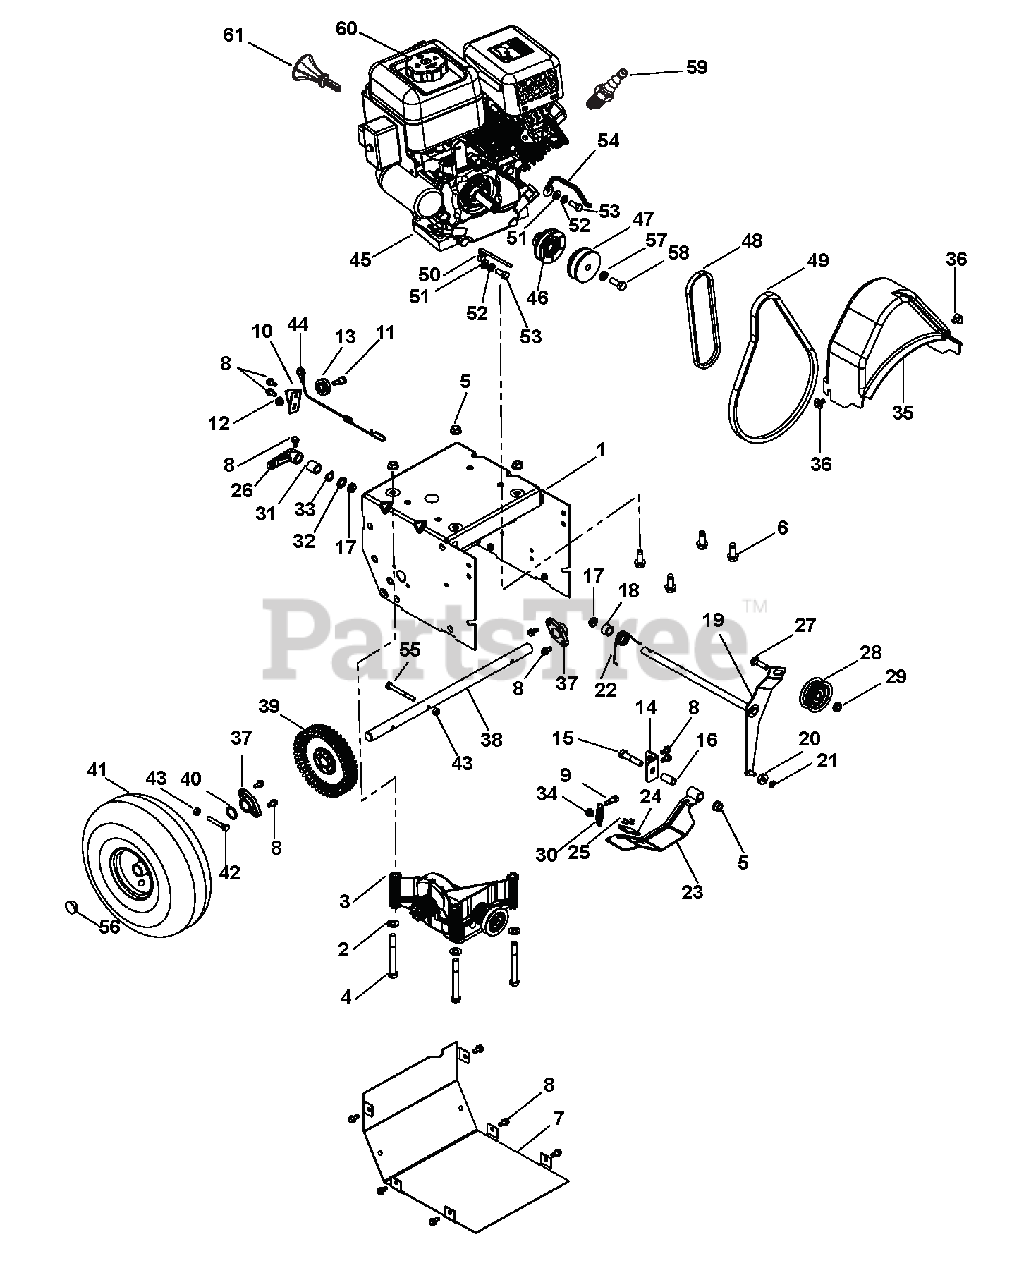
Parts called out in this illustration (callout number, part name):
1	FRAME, WELDMENT
2	@WSHR-FL-STL.406X.812X.065 YWZ
3	TRANSMISSION, GT HO W/PULLEY
4	@BLT-HEX .38-16X3.50 GR5 YWZC
5	@NUT-LK-TOP-FLG .38-16 YWZC
6	SCR-TAP .38-16X1.0 HWH YZ W/VT
7	COVER, BOTTOM
8	SCR-TAP .25-20X.50 HWH TR YWZ
9	BLT-SHLDR .31X.50 .25-20X.438
10	BRACKET, CABLE PULLEY
11	BOLT, SHLDR-.375X.375X.25-20
12	@NUT-LK-CTR-FLG .25-20 YWZC
13	PULLEY, CABLE
14	BRACKET, MOUNT - BRAKE
15	@BLT-HEX .38-16X1.75 GR5 YWZC
16	BSHG-SLV .385X.500X1.045
17	BUSHING, POLYLINER-.50 SNAPIN
18	BSHG-SLV .510X.751X.475
19	WELDMENT, ATTACHMENT IDLER ARM
20	BSHG,SLV .270 X .750 X .250
21	RG-RTNG-EXT .250X.010
22	SG-TORS .067X.88
23	BRAKE ARM W/PAD
24	PAD, BRAKE
25	RVT-POP .187 YZ
26	ARM, CLUTCH - ATTACHMENT
27	@BLT-RHDSHSQNK.31-18X1.25 G5YZ
28	KIT, FLAT IDLER
29	@NUT-LK-TOP-FLG .31-18 YWZC
30	SG-TENS .06X.46X2.00
31	BSHG-SLV .510X.751X.750
32	WSHR-FL-STL .52X.827X.062 YWZC
33	WSHR-WAVE .50X.75X.015 .13FRHT
34	@NUT-SPNLK-FLG .25-20 YWZC
35	COVER, BELT
36	SCR-TAP .25-20X.50 LGHWH TR YZ
37	BSHG .75X1.125X.65
38	SHAFT, AXLE - SINGLE SPEED
39	GEAR, AXLE 45T POLYMER
40	WSHR-FL-STL .754X1.000X.032 YZ
41	TIRE/WHEEL, 4.10-4
42	BLT-HEX .25-20X1.75 GR8 YWZC
43	@NUT-LK-CTR .25-20 YWZC
44	CABLE, LOWER TRACTION,SS & PRO
45	ENGINE, SNO-TEK 136 12OV
46	SHEAVE, DRIVE
47	SHEAVE, ENGINE
48	V-BELT, 3L-STRETCH FIT
49	V-BELT, 4L-RAW EDGE
50	BELT FINGER
51	@WSHR-FL-STL.344X.688X.065YWZC
52	WSHR-LK .312X.097 HVY YWZC
53	BLT-HEX .31-24X.75 YWZC GR5
54	FINGER, BELT
55	@BLT-HEX .25-20X2.5 GR8 YWZC
56	PLUG, HOLE - 0.75"
57	@WSHR-LK .38X.094 REG YWZC
58	BLT-HEX .38-24X1.0 YWZC GR5
59	PLUG, SPARK
60	CAP, FUEL TANK BLACK
61	KEY, PUSH/PULL LCT (2/PACKAGE)
